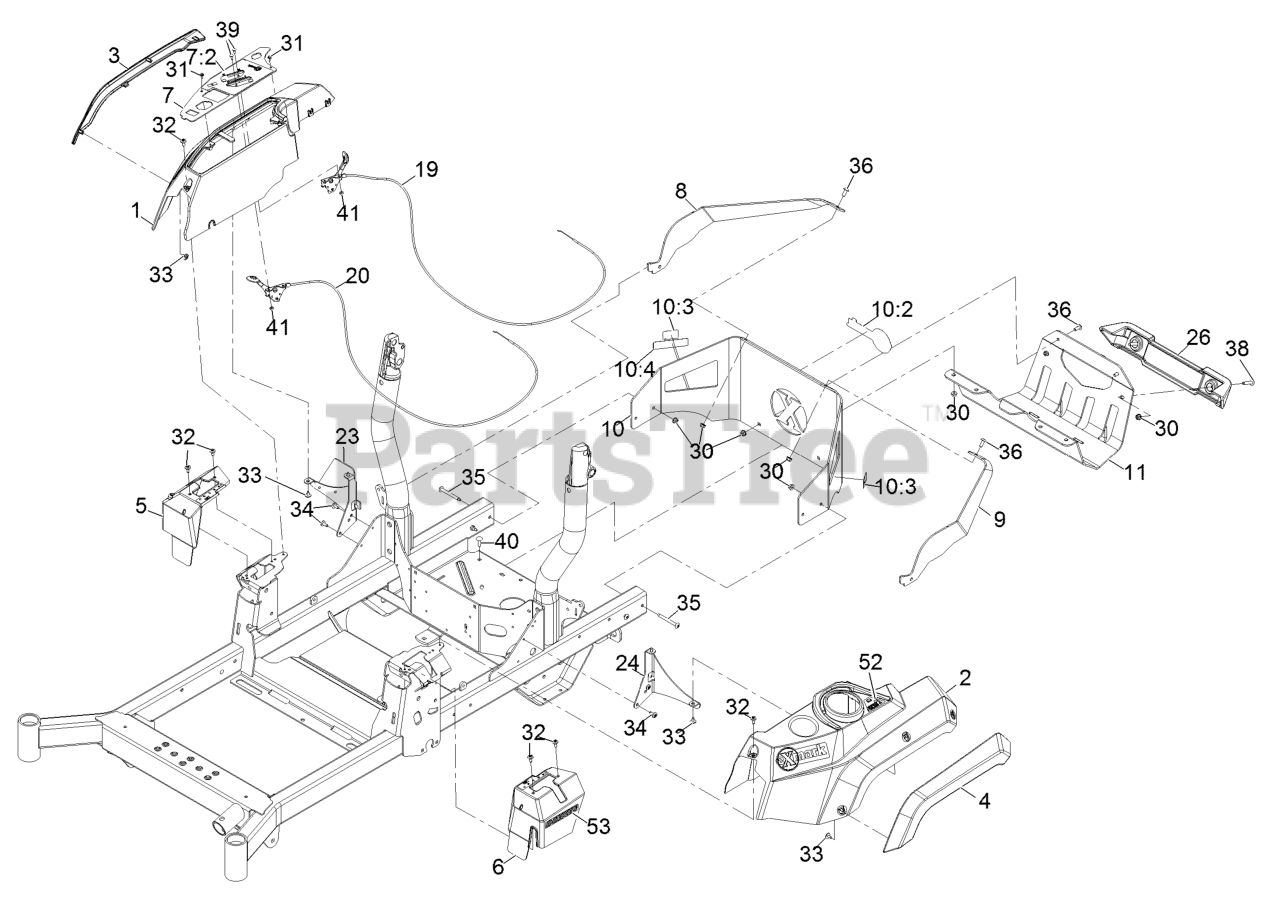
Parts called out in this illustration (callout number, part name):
1	CONSOLE-EXMARK, RH
2	CONSOLE, LH
3	FENDER-RH
4	FENDER-LH
5	COVER-CONTROL, MOTION (RH
6	COVER-CONTROL, MOTION (LH
7	ASM-CTRL PANEL W/DCL
7:2	DECAL-CONTROL PANEL
8	SUPPORT-UPPER, RH
9	SUPPORT-UPPER, LH
10	REAR GUARD ASM
10:2	DECAL-EXMARK LOGO
10:3	DECAL-WARNING
10:4	DECAL-ARRESTER, SPARK
11	GUARD-MUFFLER
19	CABLE-CONTROL, CHOKE
20	CABLE-CONTROL, THROTTLE
23	SUPPORT-CONSOLE, RH
24	BRACKET-CONSOLE, LH
30	NUT-HF, NI
31	SCREW-HWH
32	SCREW-SHOULDER
33	SCREW-TORX
34	SCREW-TORX
35	SCREW-TORX
36	SCREW-TORX
38	SCREW-TORX
39	BOLT-CARR
40	SCREW-CARR
41	NUT-LOCK, NI
52	DECAL-FILL, FUEL
53	DECAL-S-SERIES
